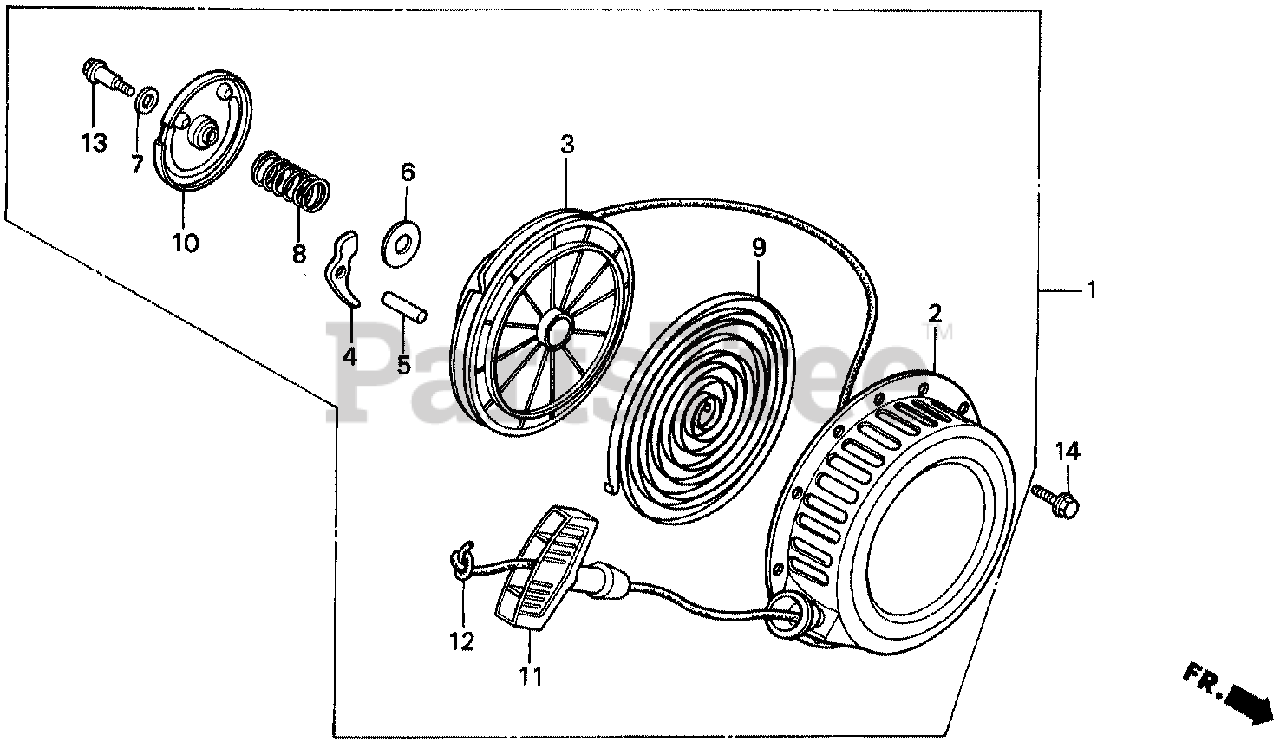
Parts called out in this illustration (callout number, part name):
1	STARTER, RECOIL
2	CASE, STARTER
3	REEL, STARTER
4	RATCHET, STARTER
5	SHAFT, RATCHET
6	PLATE A, FRICTION
7	PLATE B, FRICTION
8	SPRING, FRICTION
9	SPRING, RETURN
10	COVER, REEL STARTER
11	GRIP, STARTER
12	ROPE, RECOIL STARTER
13	BOLT, REEL COVER
14	BOLT, FLANGE (6X8)
